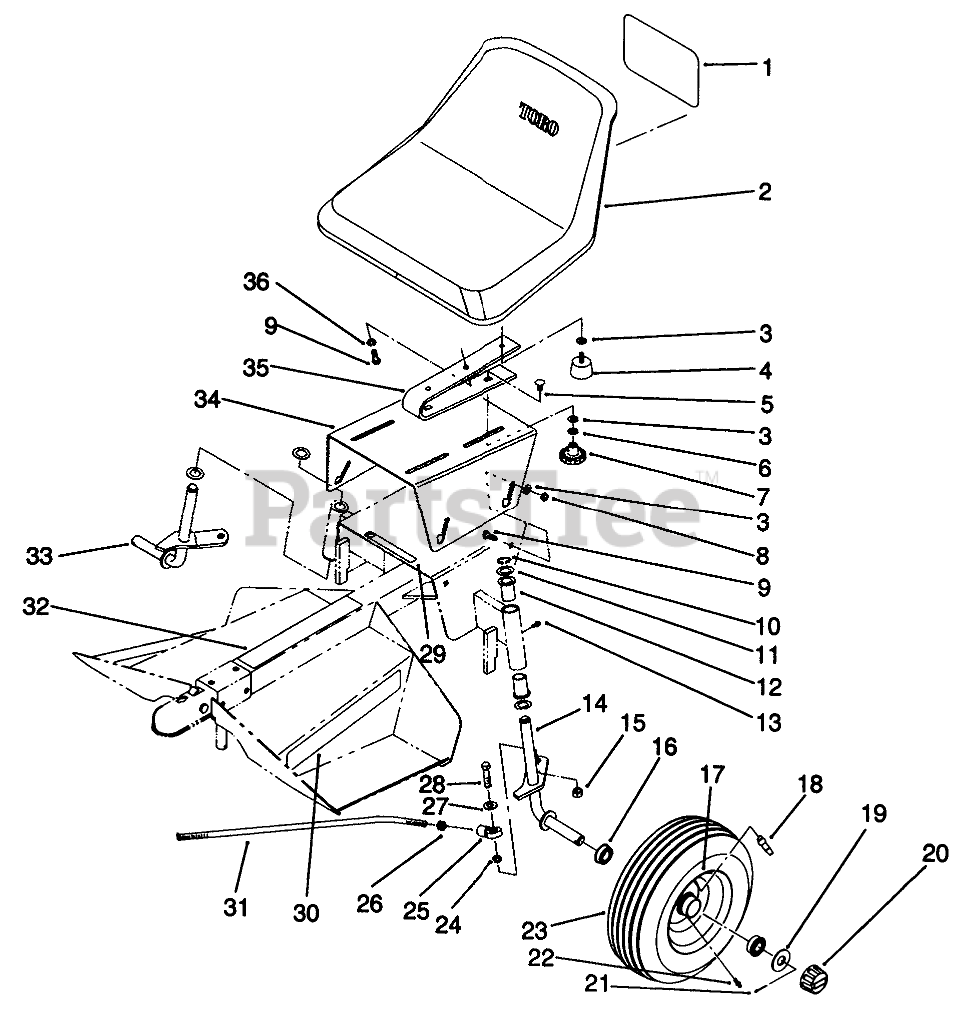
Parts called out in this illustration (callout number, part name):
1	DECAL
2	Seat
3	WASHER-PLAIN
4	RUBBER BUMPER
5	SCREW-CARR
6	WASHER-LOCK
8	NUT-LOCK, NI
9	SCREW-HH
10	E-RING
11	WASHER-THRUST
12	BUSHING PM
13	GREASE FITTING
14	Spindle -LH
15	NUT-HEX
16	Bearing
17	FRONT WHEEL
18	STEM-VALVE
19	WASHER-PLAIN
20	CAP-HUB
21	PIN-COTTER
22	FITTING-GREASE
24	WASHER
25	BALL JOINT RH
26	NUT-JAM
27	WASHER-FLAT
28	SCREW-HH
29	DECAL-INSTRUCTION
30	DECAL - PROLINE
31	STEERING ROD
32	DECAL - WARNING
33	Spindle -RH
34	Base-Seat
35	Spring Seat
36	WASHER-LOCK
